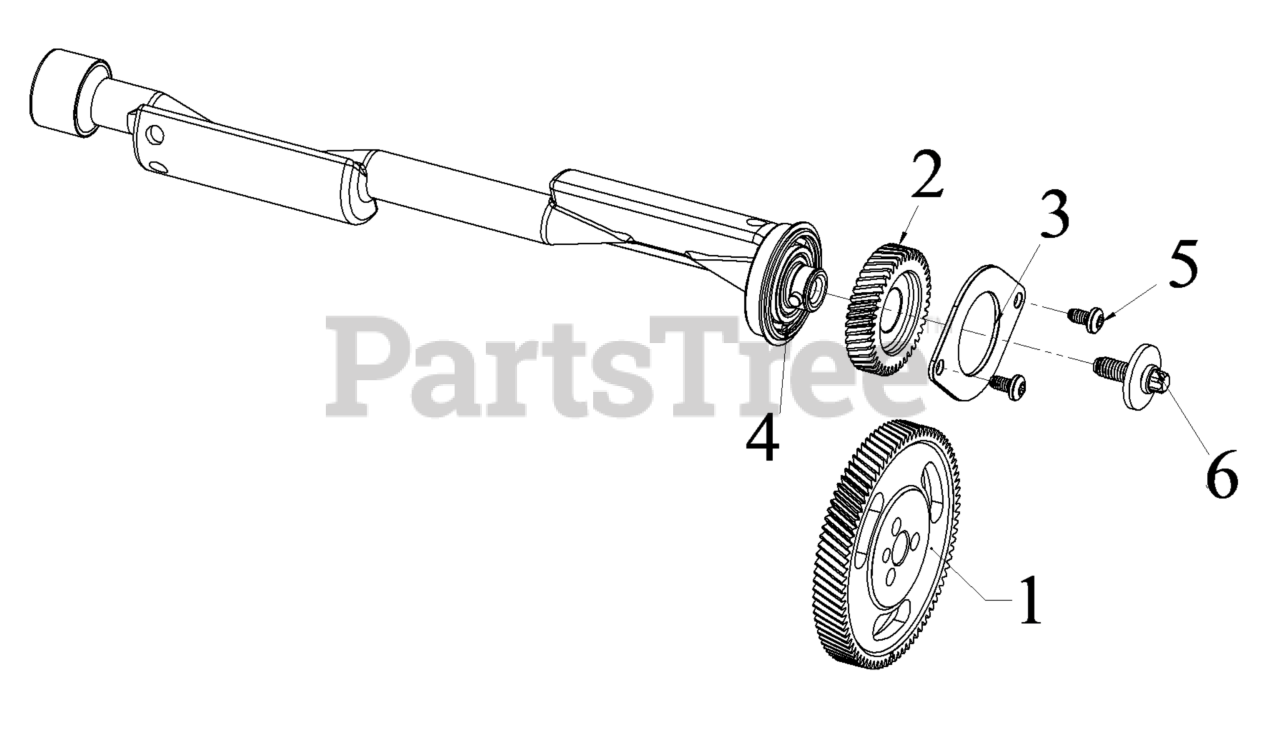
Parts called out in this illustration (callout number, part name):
1	*GEAR, BALANCER SHAFT DRIVE
2	*GEAR, BALANCER SHAFT DRIVE
3	*RETAINER, BALANCER SHAFT
4	*KIT, BALANCE SHAFT
5	*BOLT, BALANCER SHAFT RETAINER
6	*BOLT
